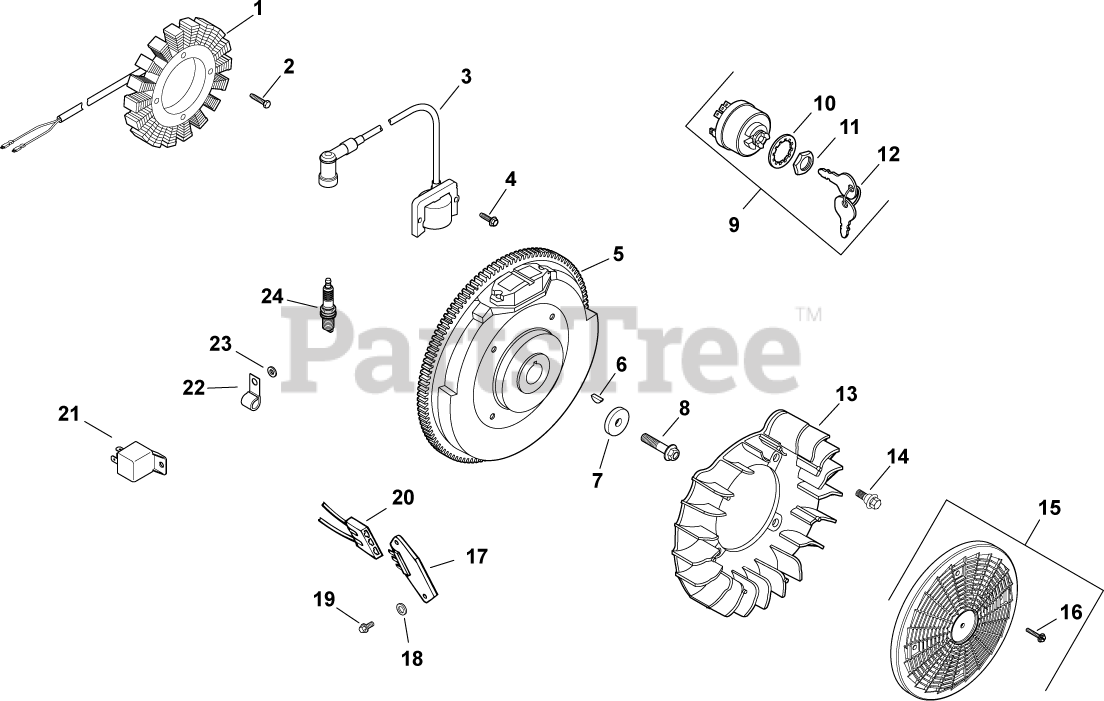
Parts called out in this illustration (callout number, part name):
1	KIT, 15 / 20 AMP STATOR
2	SCREW, M5X0.8X25 - (#25086402S)
3	KIT, MODULE IGNTN (CDI FIXED)
4	SCREW, FLG THD FRM M5X.8X20-(#25086399S)
5	FLYWHEEL, PAINTED-USE 24 025 59-S
6	KEY, 3/16" X 5/8"
7	WASHER, FLAT 13/32"
8	SCREW, FLG M10X1.5X45 - (#25086361S)
9	SWITCH ASSY, KEY (KM)-USE 25 099 32-S
10	WASHER, INTERNAL TOOTH
11	NUT, KEY SWITCH
12	KEY, SET -USE 48 340 01-S
13	FAN USE 24 755 253-S
14	BOLT, SHOULDER
15	KIT, GRASS SCREEN
16	SCREW, FLG SEMS M4X.7X25
17	REG/RECT-15 AMP (KM)-USE 41 403 10-S
18	WASHER, FLAT 7/32"
19	SCREW, PHL HD #11-16X7/8"
20	CONNECTOR, BODY (KM)-USE 25 155 41-S
22	CLIP, CABLE
23	WASHER, FLAT 1/4" (O.D. 1/2")
24	PLUG, SPARK (STD)
